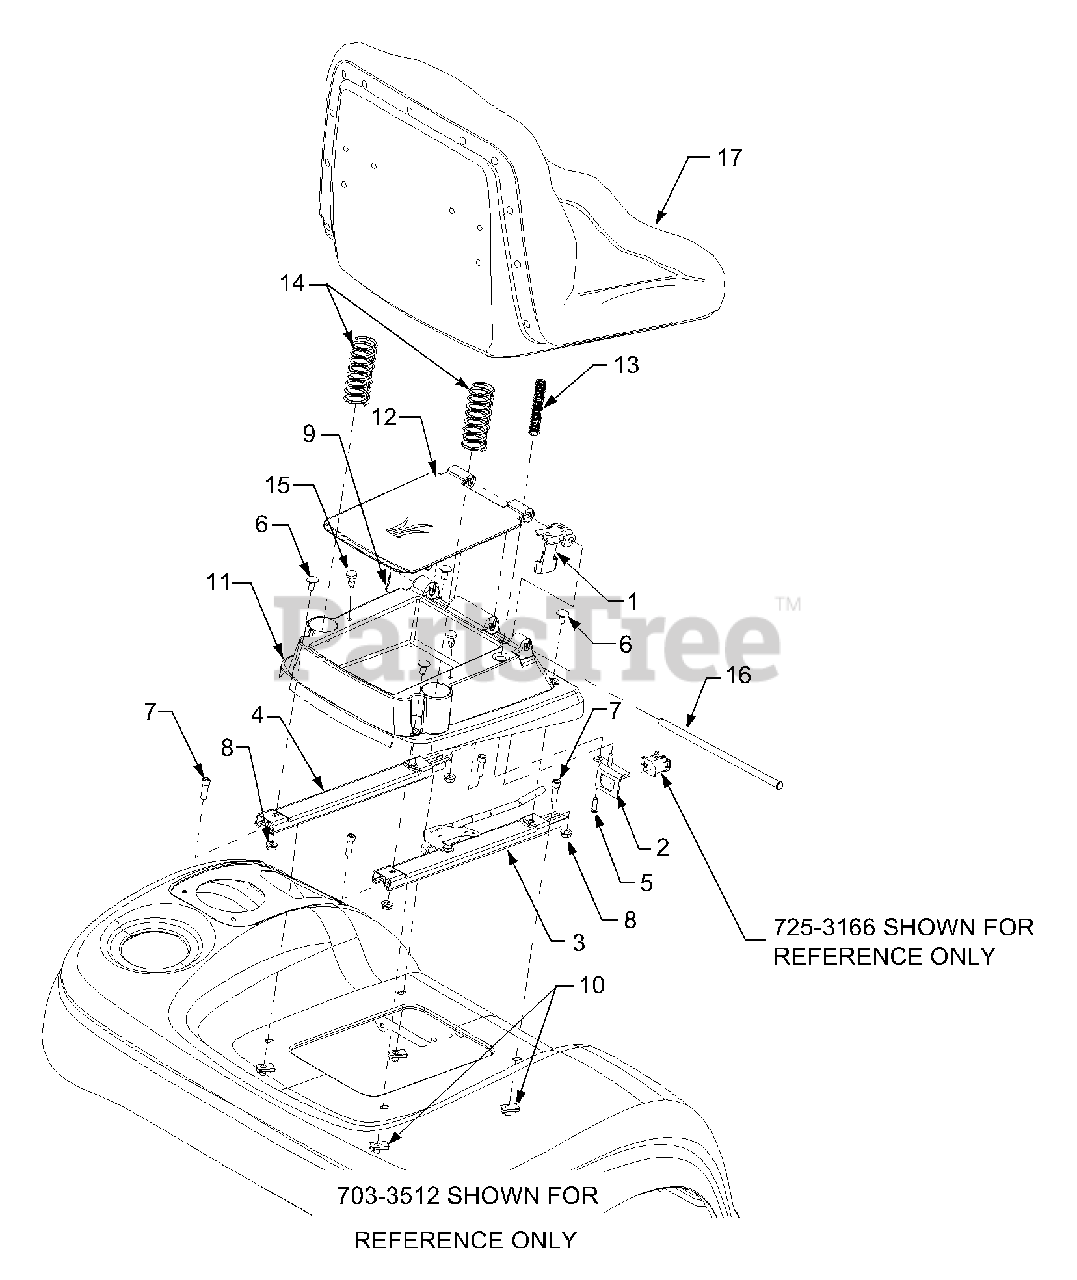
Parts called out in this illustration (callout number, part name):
1	Bracket, Seat Switch
2	Bracket, Switch Mounting
3	Track, Seat, w/Latch
4	Track, Seat, w/o Latch
5	Screw, Pan Torx Hd., #12-14 x .5
6	Carriage Bolt, 5/16-18 x .62
7	Screw, Pan Torx Hd 5/16-18 x 1.0
8	Nut, Hex Flange Lock, 5/16-18
9	Pin, Cotter, 3/32 x .75
10	Speed Nut, U-Type, 5/16-18
11	Base, Seat
12	Lid, Tlbx
13	Spring, Compression
14	Spring, Compression
15	Bumper
16	Rod, Seat Pivot
17	Seat, High Back
18	Bracket, Seat Spring Support
19	Screw, Pan Hd., 5/16-18 x 1.0
